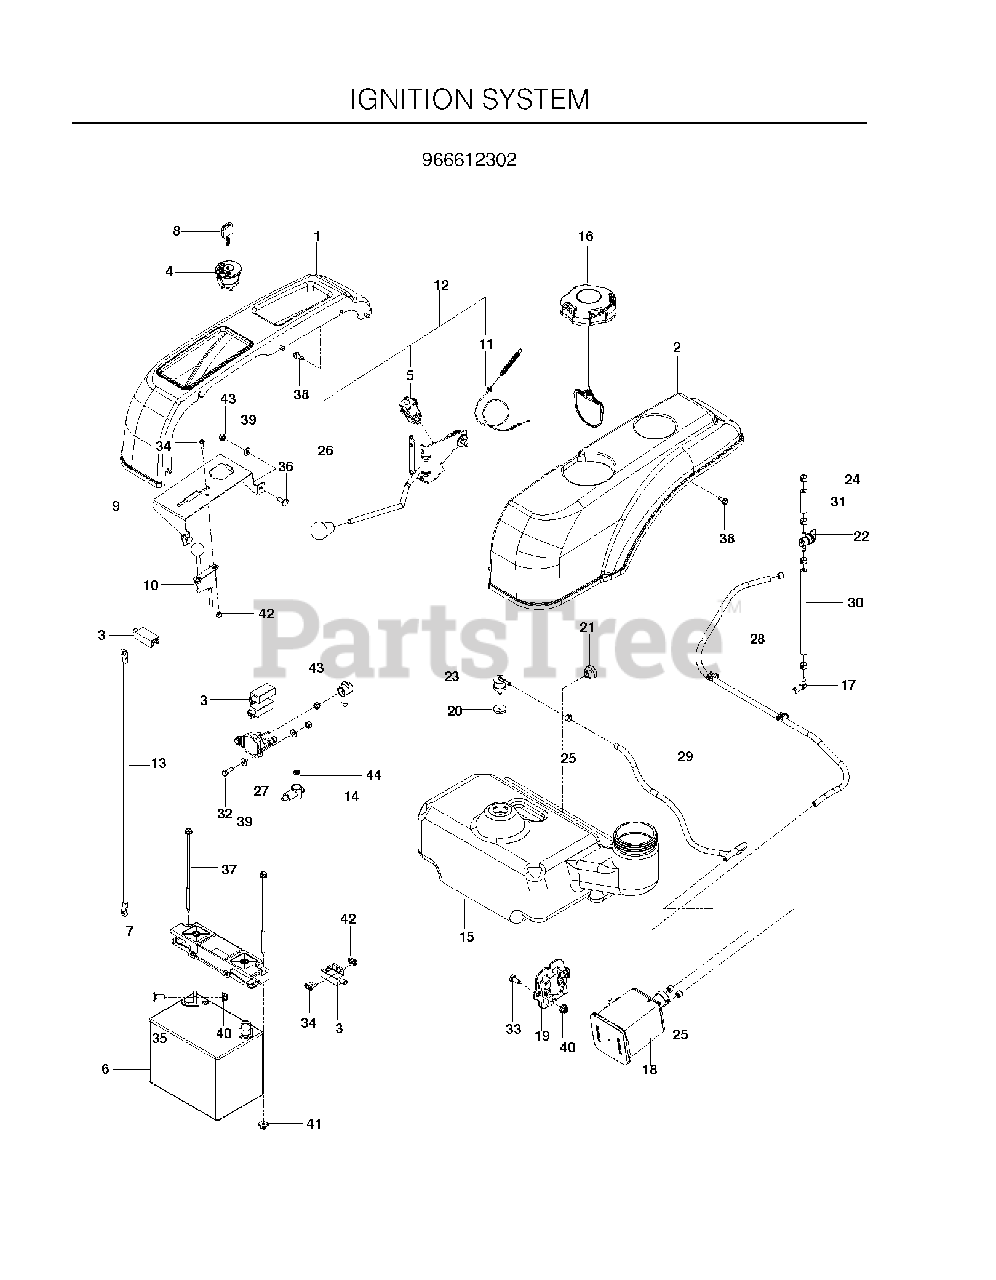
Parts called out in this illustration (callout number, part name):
1	FENDER, RZ 30/38 RT
2	FENDER, RZ 30/38 LT
3	SWITCH, INTERLOCK
4	RP IGNITION SWITCH
5	SWITCH INTERLOOK PUSH-IN
6	BATTERY, 12 V 330 AMP
7	BATTERY HOLD DOWN
8	KEY
9	MOUNT, CONTROLS, BLK
10	CABLE, THROTTLE
11	CABLE.CLUTCH.38".SERVICE
12	ASM, CLUTCH ENGAGE W/CABLE
13	BATTERY CABLE, NEGATIVE
14	TERMINAL COVER-SM
15	TANK, FUEL EPA
16	CAP, FUEL
17	STEM, FUEL TANK
18	CANNISTER, CARBON
19	BRACKET, CANISTER
20	GROMMET, CHECK VALVE
21	RUBBER GROMMET
22	FUEL VALVE
23	VALVE.FUEL.CHECK
24	HOSE CLAMP
25	CLAMP, HOSE
26	KNOB - SHIFT
28	FUEL LINE 33"
29	HOSE, FUEL, 3/16" X 20"
30	HOSE 1/4 X 8
31	HOSE 1/4 X 2"
32	HCS 1/4C X 3/4 HCS
33	HCS 5/16-18 X 5/8 GR 5 ZD
34	SCREW #10-24 X 5/8
35	BOLT 5/16C X 3/4" CARRIAGE
36	RHSNB 1/4C X 3/4
37	Bolt, 1/4-20 X 7.5
38	SCREW 1/4 X 5/8
39	WASHER 1/4 SAE
40	5/16-18 NYLOC FLANGE NUT
41	PUSH NUT-NYLON
42	NUT 10-24 NYLOC
43	RP_NUT 1/4-20 NYLOC
44	JAM NUT 1/4C (2 2 PW01)
